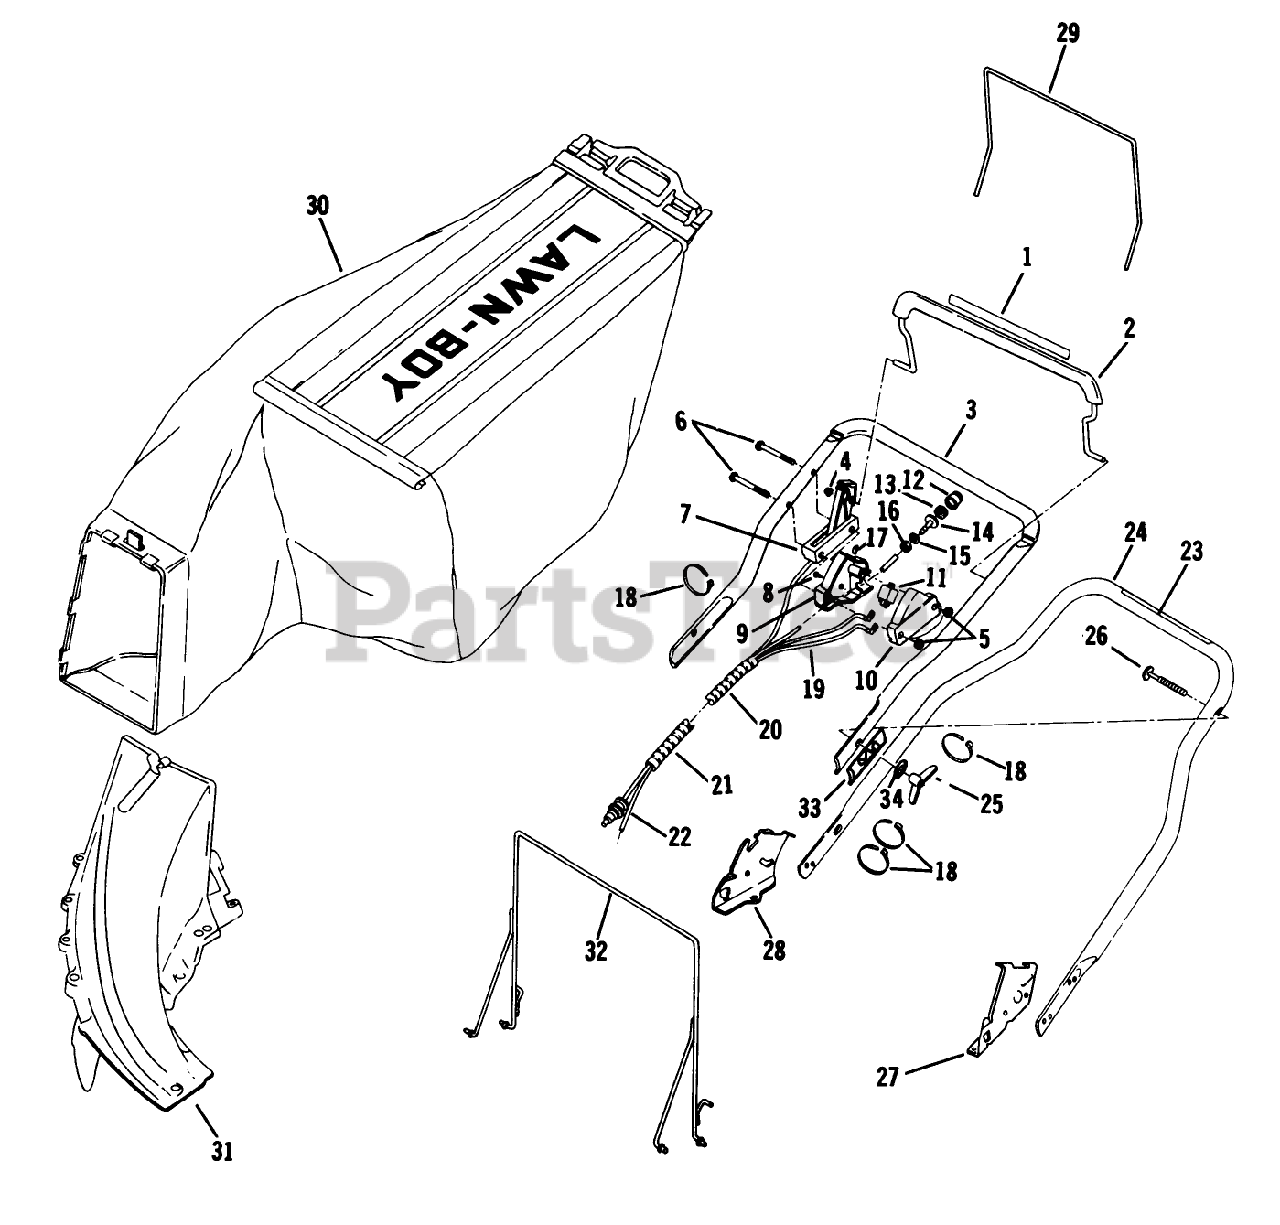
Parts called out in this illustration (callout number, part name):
5	NUT C/LOCK E
6	SCREW
7	BBC CONTROL SER AY
11	SWITCH AY
13	FILTER S
16	LOCKNUT S
25	NUT-WING
26	BOLT QUALITY
29	HANGER
32	HANGER AY
33	BRACKET R/B 613462
34	WASHER-CURVED
